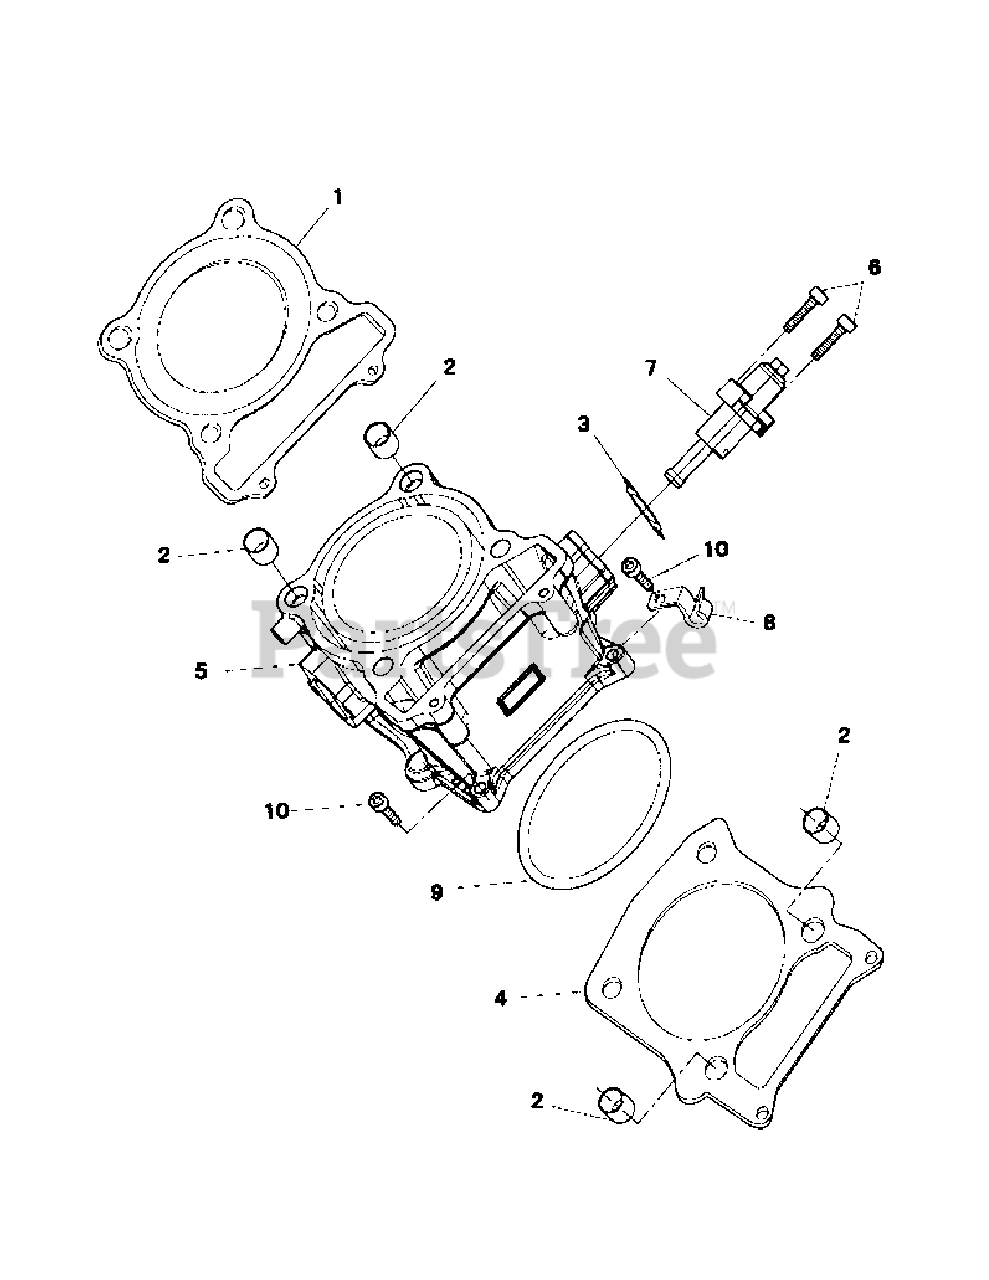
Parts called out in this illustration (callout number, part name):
1	Gasket-Cylinder Head
3	Tensioner-Gasket
4	Gasket-Cylinder Body
5	Cylinder Body-Comp
6	Screw-Cylinder M6 X 25 Inner
7	Tensioner-Comp
10	Flange Bolt M6 X 25
